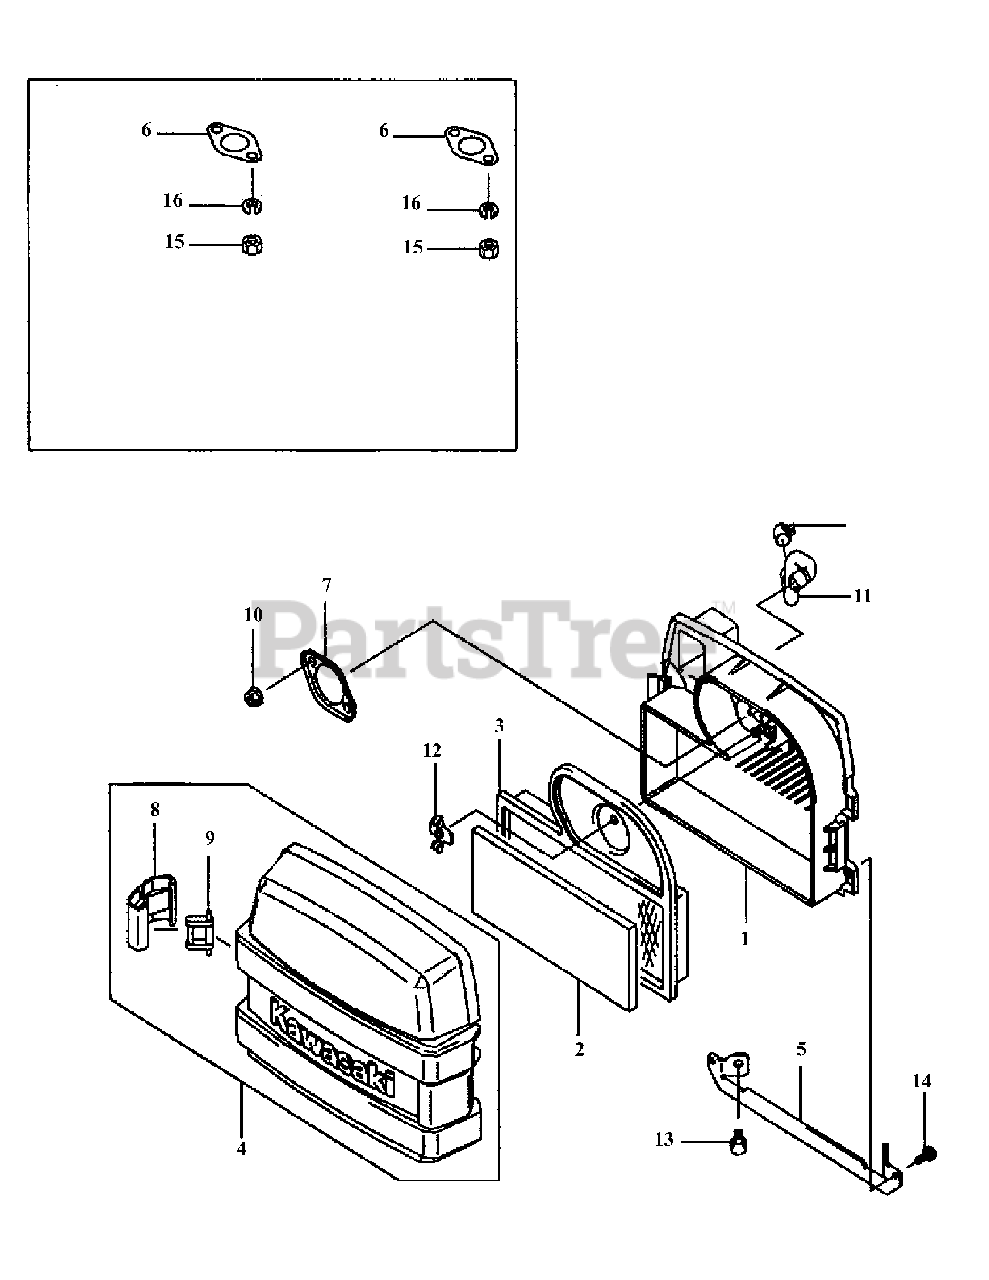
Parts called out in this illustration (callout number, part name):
1	Case, Air Filter
2	Element, Pre Filter
3	Element, Air Filter
4	Case, Assembly Air Filter
6	Gasket, Muffler
8	Hook, Air Filter
13	Bolt, Flanged
14	Screw, Pan
15	Nut, Hex Small
16	Washer, Spring
